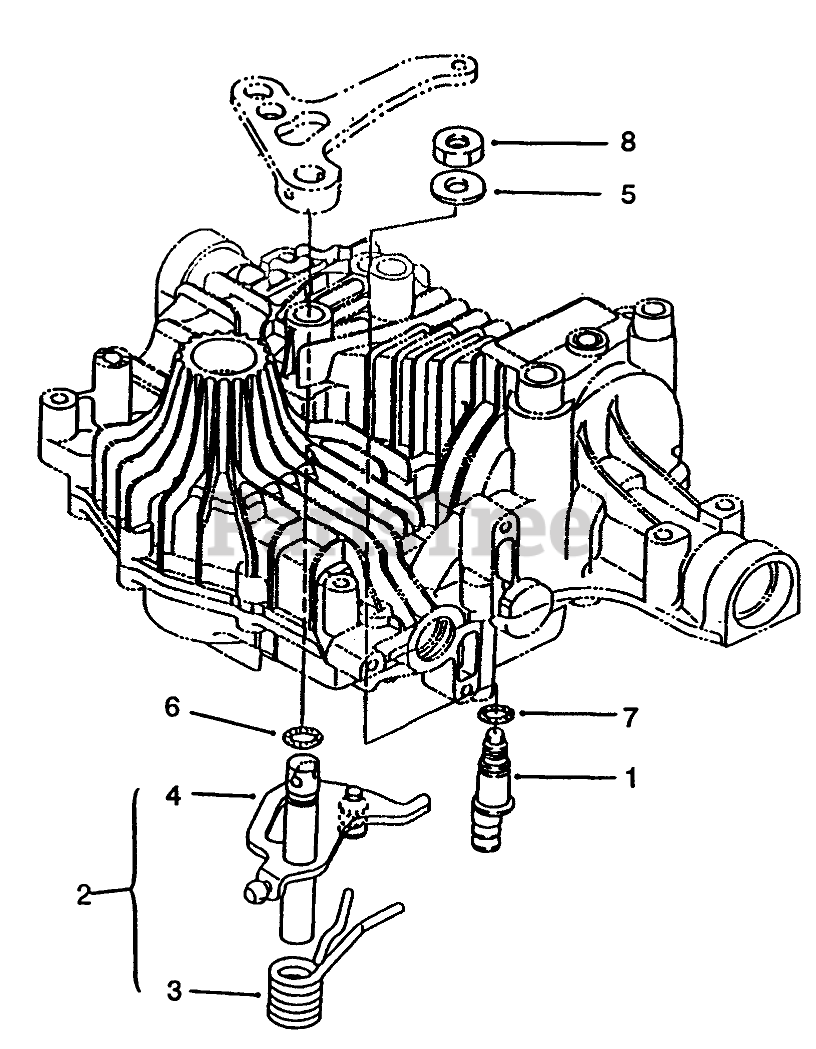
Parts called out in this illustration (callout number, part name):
1	Fulcrum (Only On: 72083, 72043 72103, 72063)
2	Shaft ASM INC 3-4 (Only On: 72083, 72043, 72103, 72063)
5	Washer (Only On: 72083, 72043, 72103, 72063)
6	Packing (Only On: 72083, 72043, 72103, 72063)
7	Packing (Only On: 72083, 72043, 72103, 72063)
8	Nut (Only On: 72083, 72043, 72103, 72063)
